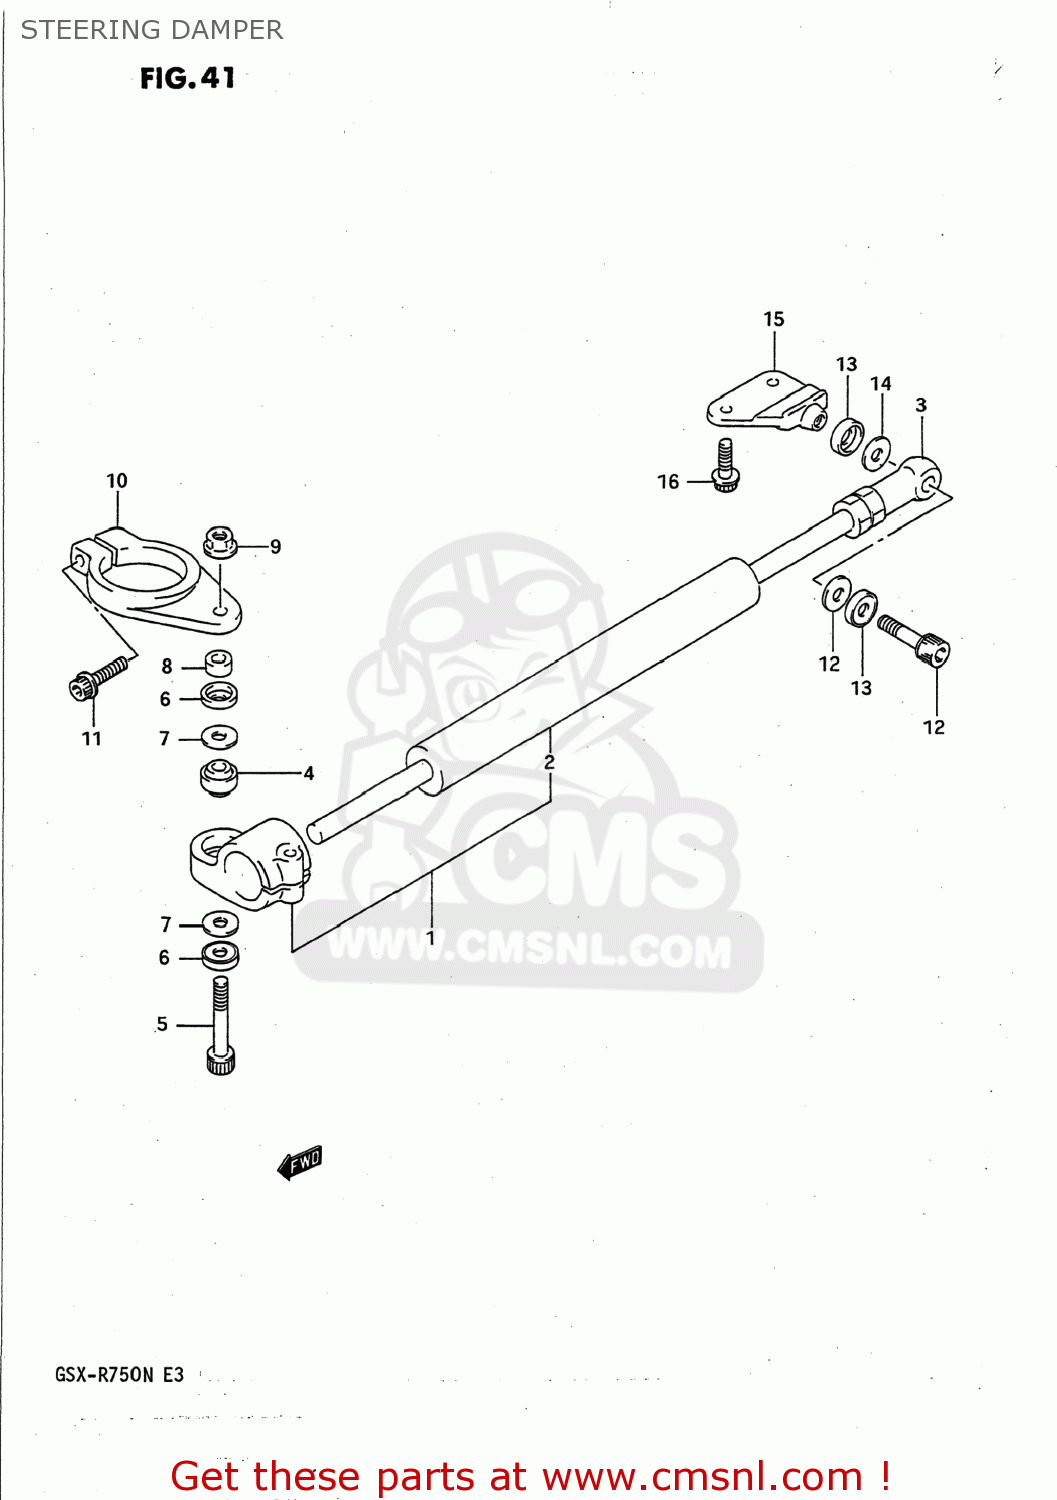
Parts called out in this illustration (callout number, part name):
1	DAMPER ASSEMBLY,STEERING
2	DAMPER,STEERING
3	PILLOW BALL,ROD END
4	BEARING(8X17.5X11)
5	BOLT
6	7
7	SHIM
8	SPACER (8.4X14X6)
9	NUT
10	BRACKET,STEERING DAMPER
11	BOLT
12	BOLT, FRONT RH
13	14
14	SHIM
15	BOSS,STEERING DAMPER
16	BOLT 6X20
